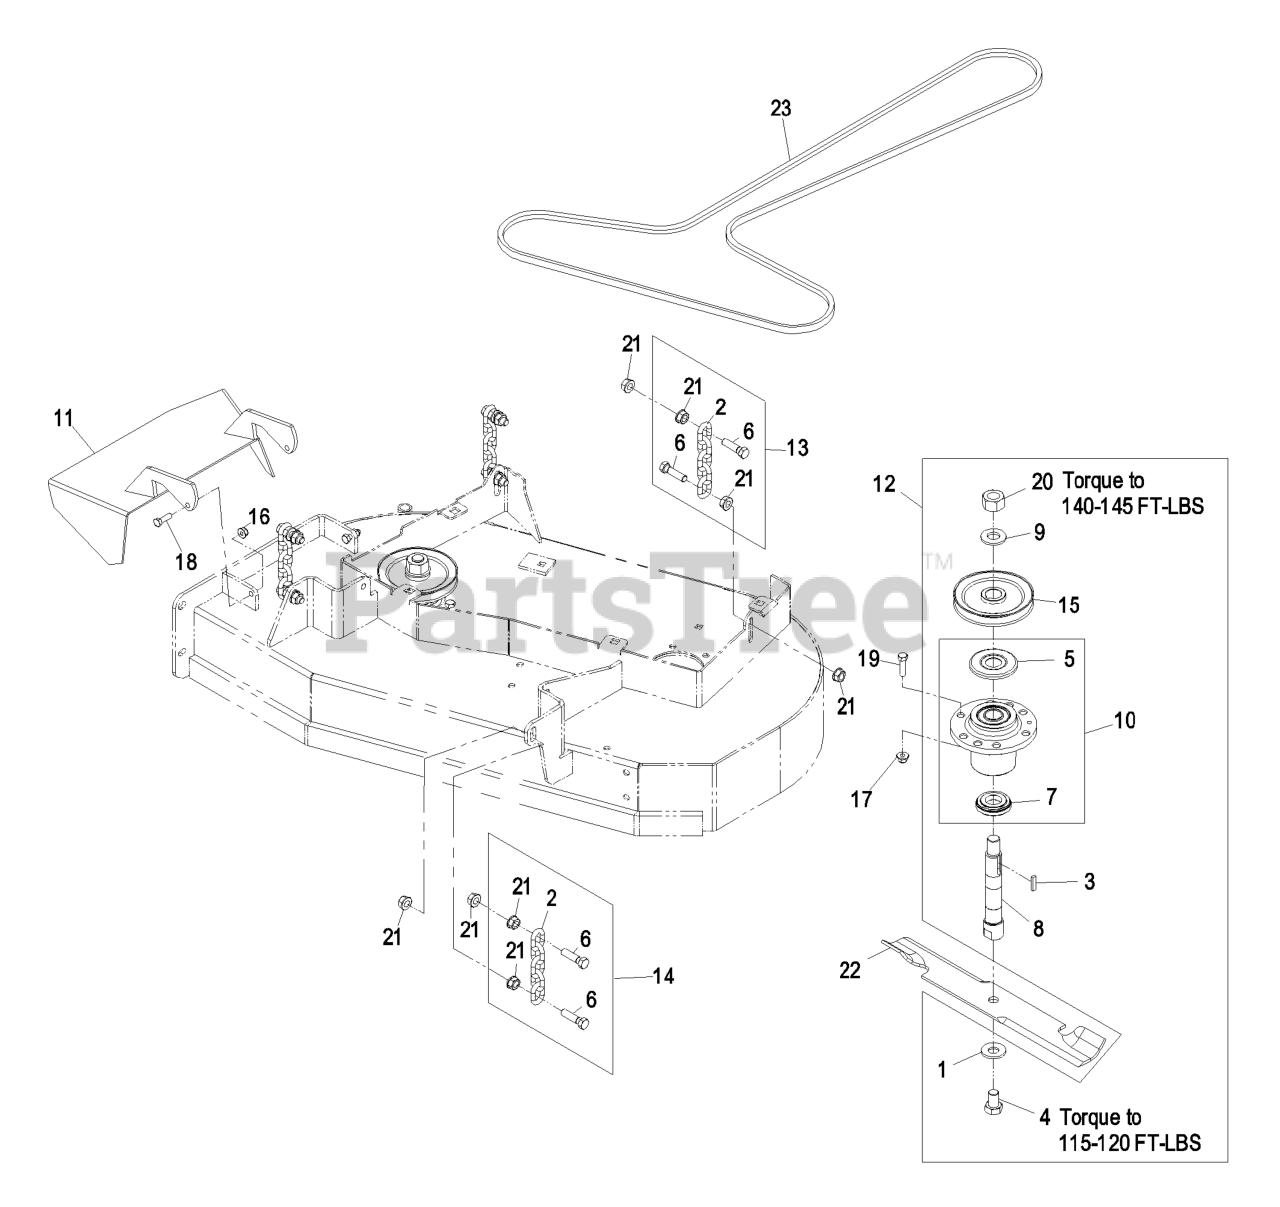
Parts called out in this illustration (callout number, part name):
1	WASHER-SPRING
2	CHAIN-LIFT, DECK
3	KEY-RECTANGLE
4	SCREW-CAP
5	GUARD-BEARING, TOP
6	SCREW-HH
7	SPACER-GUARD, BOTTOM
8	SPINDLE,SHAFT
10	KIT, CUTTER HOUSING
11	WLD,CHUTE
12	ASM,CUTTER HOUSING COMPLE
13	DECK CHAIN ASM
14	DECK CHAIN ASM
15	PULLEY,SPINDLE
16	NUT-HF, NI
17	NUT-HF, NI
18	SCREW-HH
19	SCREW-HH
20	NUT-HH
23	BELT,A107.40
